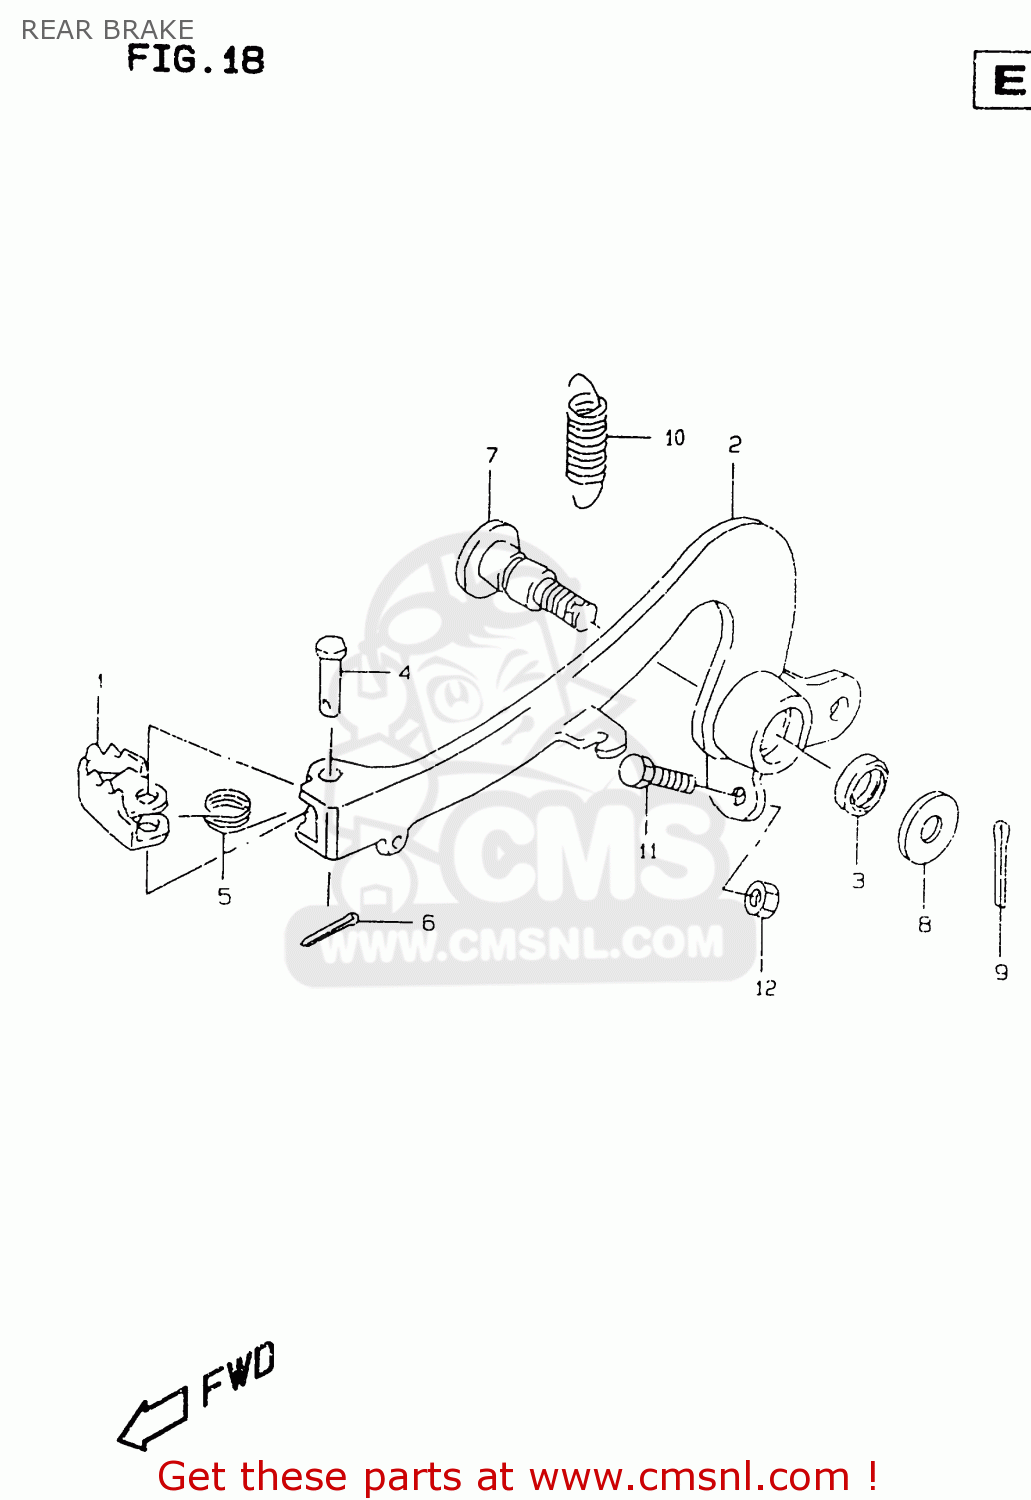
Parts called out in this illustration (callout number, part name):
1	PEDAL,BRAKE
2	ARM,BRAKE PEDAL
3	SEAL,OIL(15X21X3)
4	PIN(6X23.5)
5	SPRING
6	PIN
7	SHAFT,BRAKE PEDAL
8	WASHER
9	PIN 20X20
10	SPRING
11	BOLT(6X23)
12	NUT 6MM
